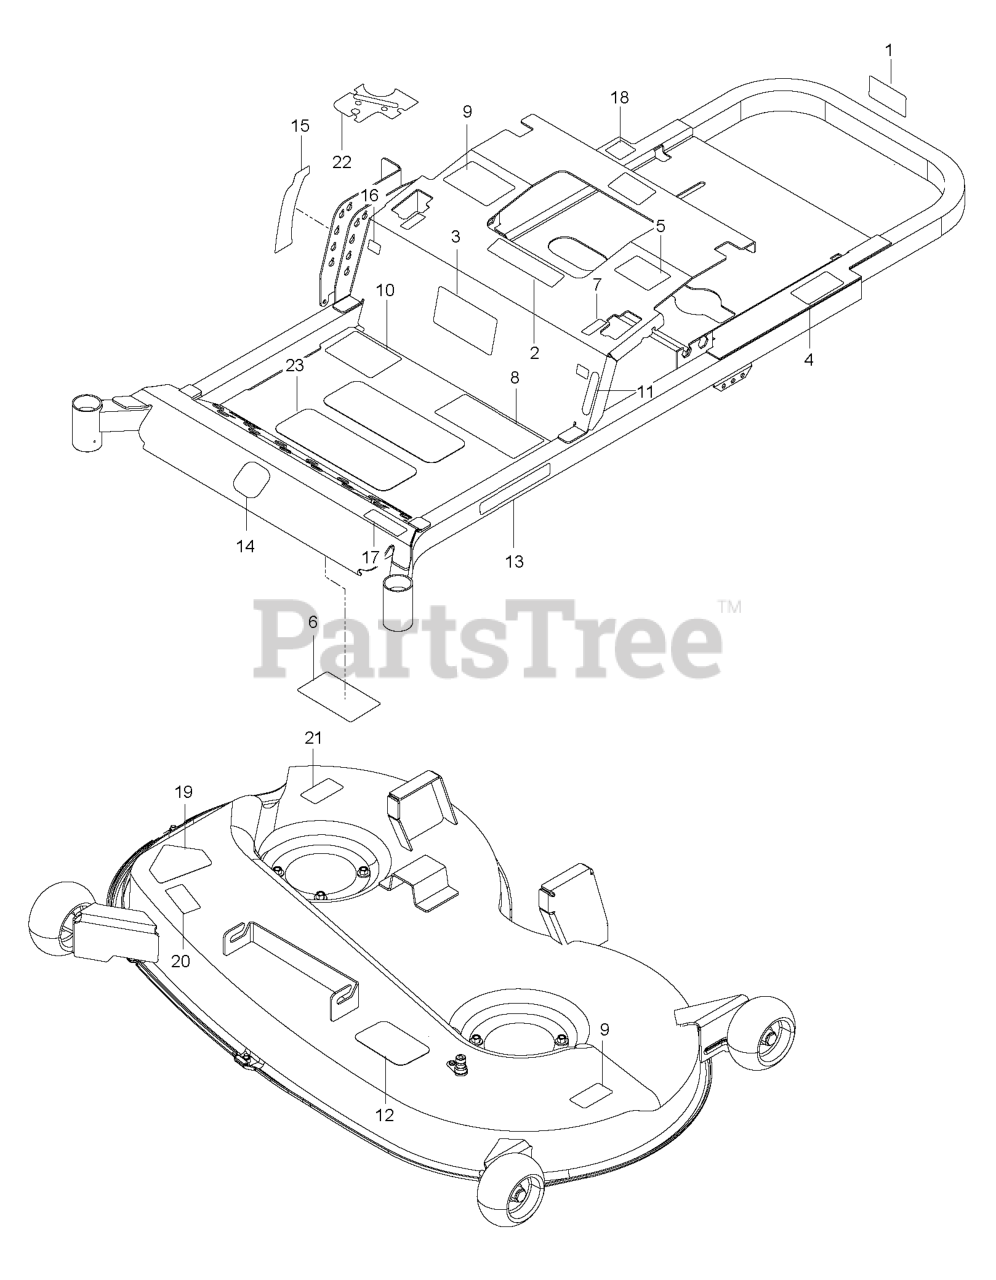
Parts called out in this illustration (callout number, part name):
1	DECAL, PROP. 65
2	EURO DECAL-BATTERY WARNIN6
3	DECAL, START
4	DECAL, DO NOT TOW
5	DECAL, EXITING MOWER
6	DECAL, SERVICE
7	DECAL, MOTION CONTROL
8	DECAL, SAFETY WARNING
9	DECAL, CUSTOMER RESPNSIBILITY
10	DECAL, WARNING
11	DECAL, PARK BRAKE
12	DECAL, BELT ROUTING
13	RP.DECAL.BADGE.170MM.TEXTLOGO
14	DECAL, CROWN H 70MM
15	DECAL, HEIGHT
16	DECAL, F.S.T.
17	DECAL, RZ4621 (BF UNIT)
18	DECAL, ECM, AUSTRALIA
19	DECAL, CPSC
20	DECAL, EURO SEVERING
21	DECAL.DECK.6MIL./DEF.SHLD.WARN
22	DECAL, CTRL PANEL HUS WO CHOKE
23	ANTI-SKID PAD
